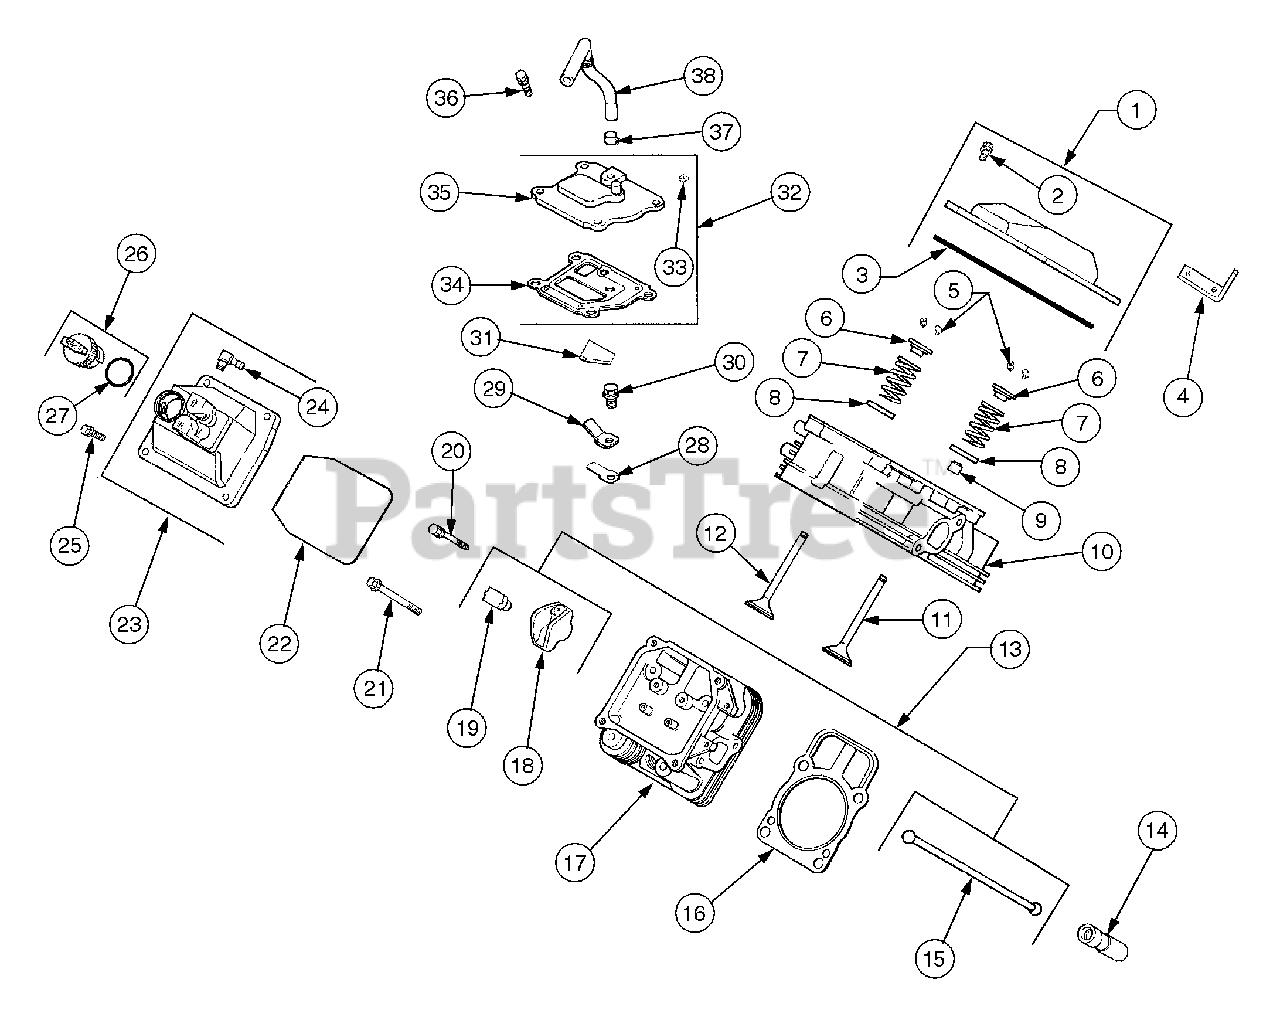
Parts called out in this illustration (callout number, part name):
1	Kit, Valve Cover
2	Screw, Shoulder
3	O-Ring, Valve Cover
4	Strap, Lifting
5	Kit, Retainer
6	Cap, Valve Spring
7	Spring, Valve
8	Retainer, Spring
9	Seal, Valve Stem
10	Head Assembly, #1 Cylinder
11	Valve, Intake Std
12	Valve, Exhaust Std
13	Kit, Valve Train
14	Lifter, Valve
16	Gasket, Cylinder Head
17	Head Assembly, #2 Cylinder
19	Pivot, Rocker Arm
20	Screw, Hex Flng, M6 x 1.0 x 34
21	Screw, Hex Flng, M10 x 1.5 x 90
22	O-Ring, Valve Cover
23	Cover, Fuel Pump Vlv
24	Connector, 90°.
25	Screw, Shoulder
26	Cap Assembly, Oil Fill
27	O-Ring
28	Reed, Breather
29	Retainer, Breather Reed
30	Screw, Hex Flng, M5 x 0.8 x 10
31	Filter, Breather
32	Kit, Breather
33	Plug, Allen Hd 1/8 Pipe
34	Gasket, Breather
35	Cover, Breather
36	Screw, Hex Flng M6 x 1.0 x 20
37	Clamp, Breather
38	Hose, Breather
